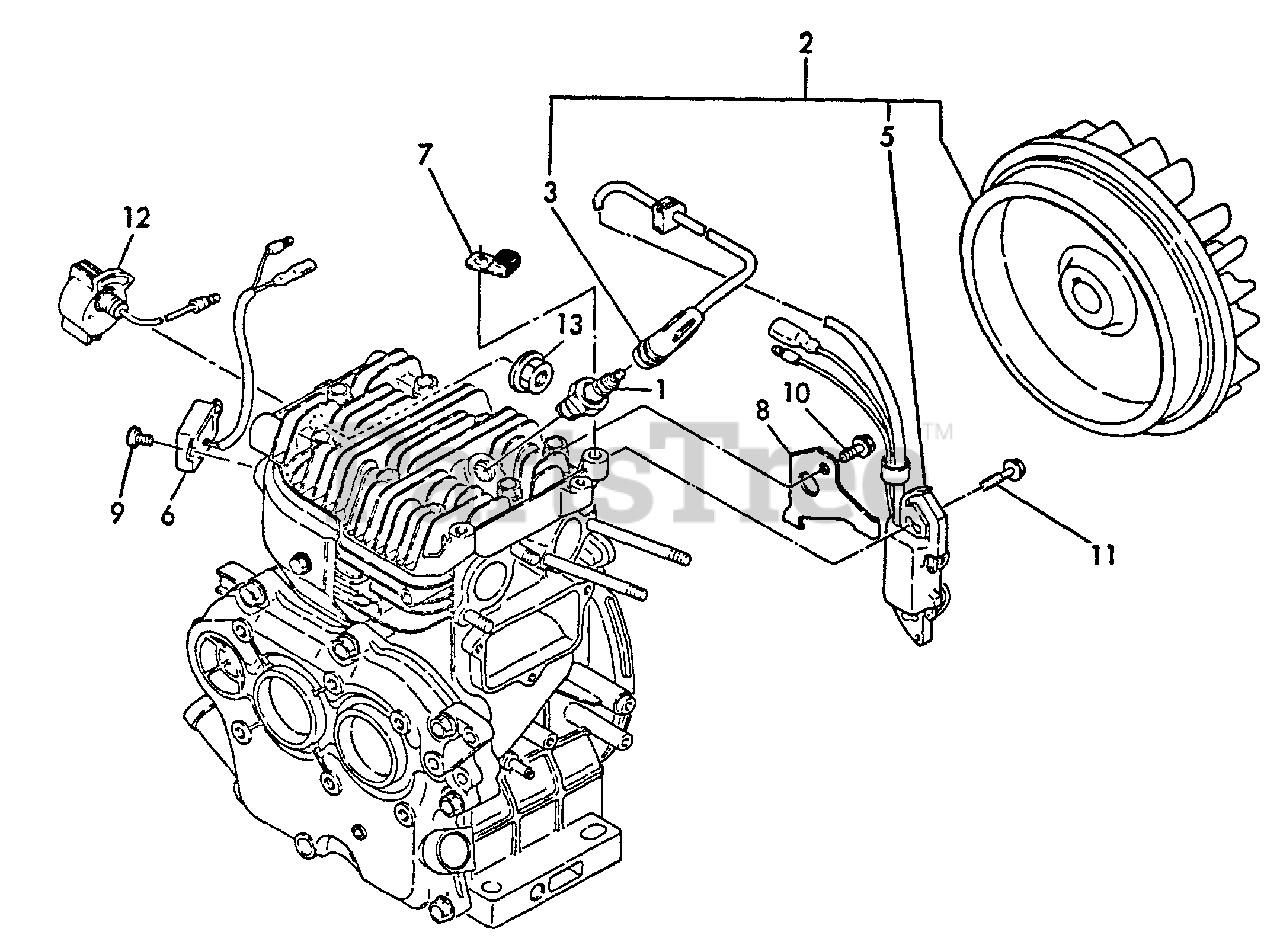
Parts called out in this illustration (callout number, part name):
1	SPARK PLUG
2	FLYWHEEL W/MAGNET
3	CAP, PLUG
5	COIL, IGNITION
6	IGNITER
7	CLAMP
8	CLAMP
9	SCREW - 5×10
10	BOLT - 6×8 -- PLATED
11	BOLT - 6×30
12	IGNITION SWITCH ASSY
13	U-NUT M8
